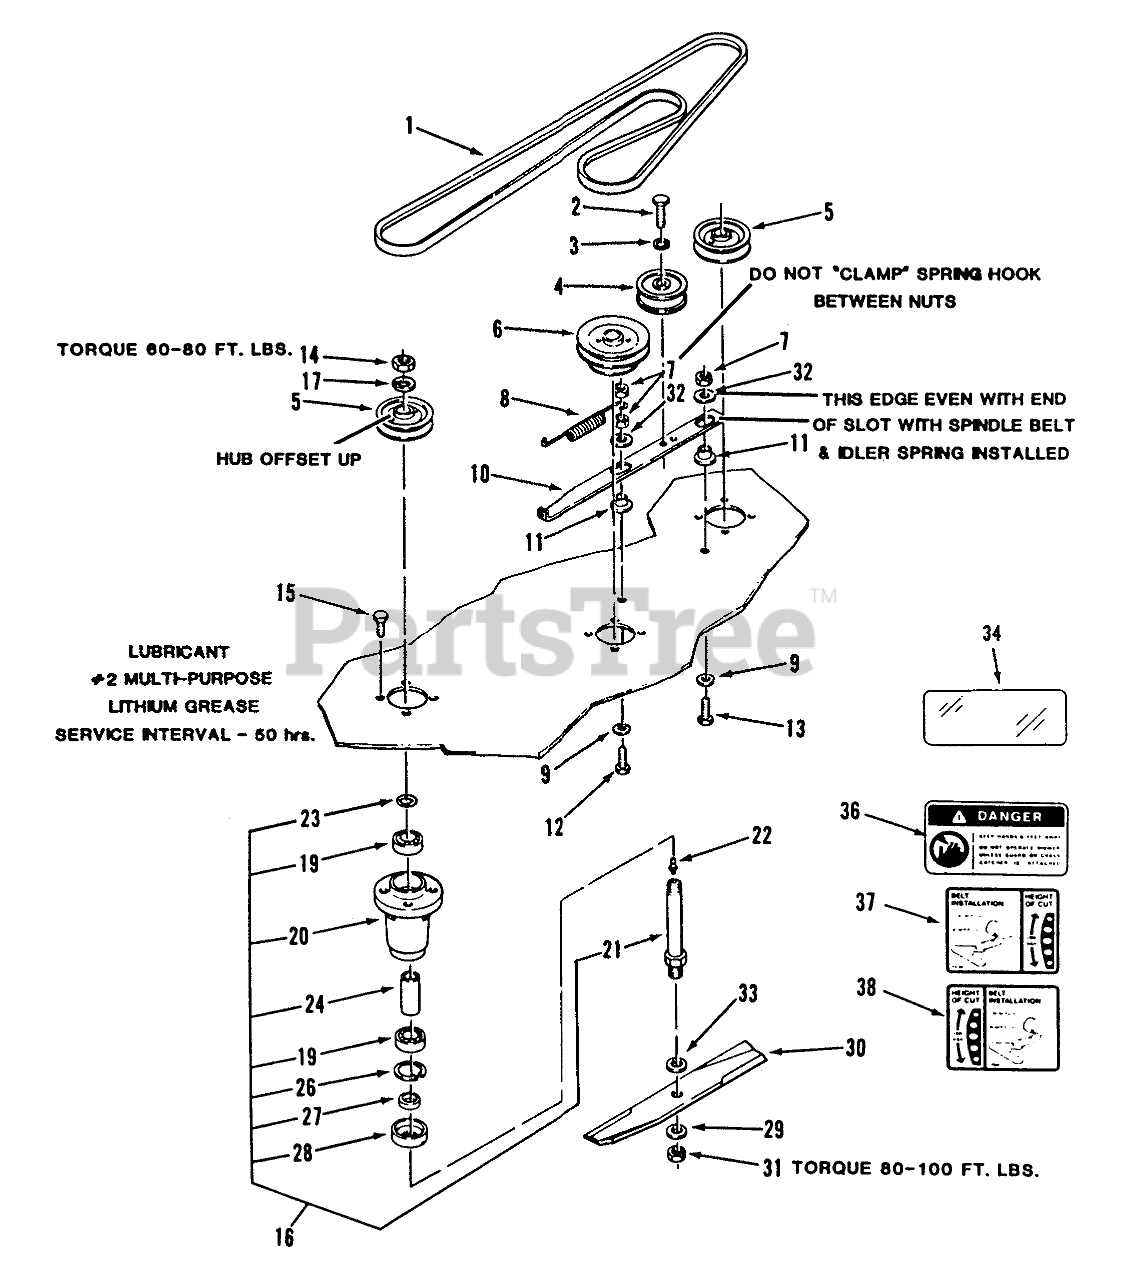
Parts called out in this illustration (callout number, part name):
1	V-BELT
2	BOLT HEX SPECIAL
3	LOCKWASHER
4	Idler Pulley
5	PULLEY-BLADE, DRIVE
6	PULLEY-MOWER, 48IN
7	NUT
8	SPRING-EXTENSION
9	WASHER
10	BAR-IDLER SUPPORT
11	SPACER-BUSHING
12	Bolt
13	Bolt
14	X-REF 3220-6
15	Bolt
16	Spindle Assembly
17	Lockwasher
19	BEARING-BALL
20	HOUSING-SPINDLE
21	SHAFT-SPINDLE
22	Zerk
23	O RING
26	Ring-Snap
27	SPACER-BLADE
28	CUP-SPINDLE
29	SpeciaI Washer
30	BLADE KIT (3 PACK)
31	X-REF 3220-7
32	WASHER
33	Washer
34	DECAL-OVERLAY
36	Danger Decal
37	DECAL-HEIGHT & BELT
38	DECAL-HEIGHT & BELT
